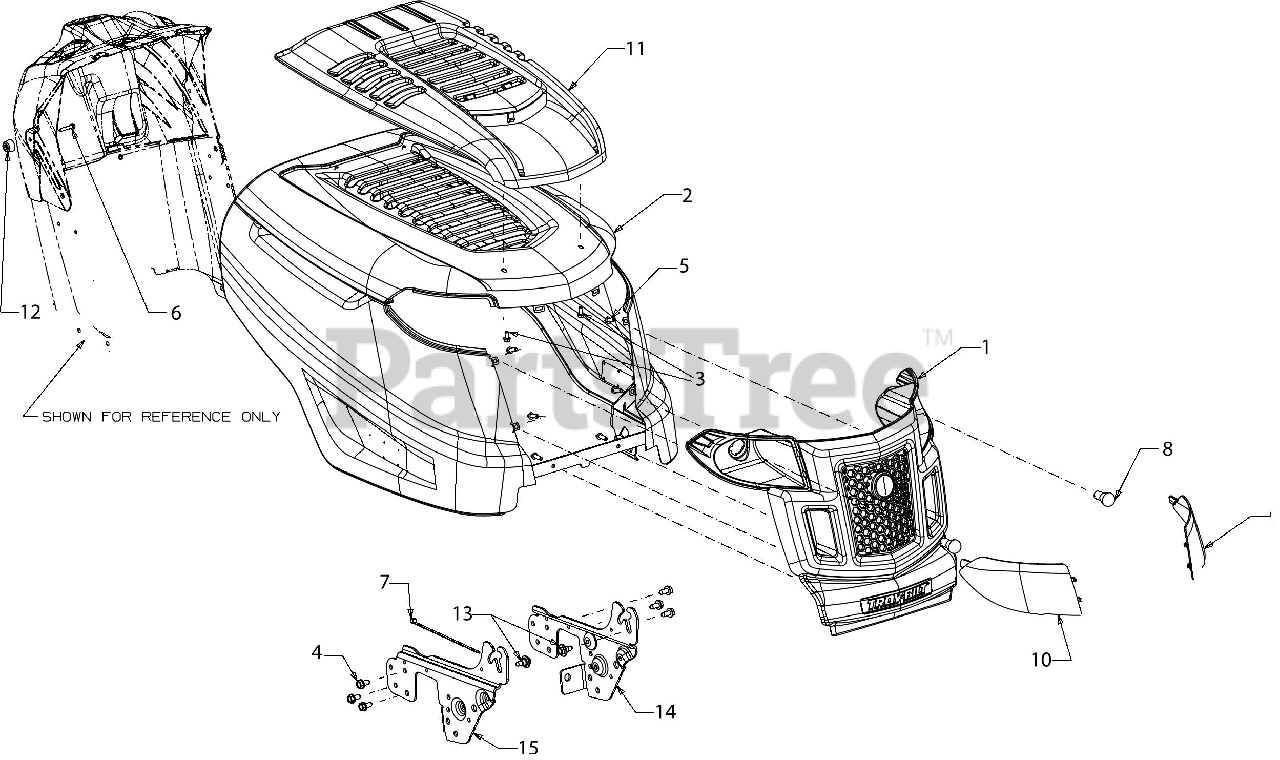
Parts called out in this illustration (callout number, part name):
1	GRILLE ASSEMBLY (TROY-BILT)
1	LABEL-TROYBILT/GEAR
3	HEX SCREW 1/4-15 x .50
4	SCREW 5/16-18 x .750
5	SCREW 1/4 x .750
6	SCREW #12 x 1.15
7	7" CABLE TIE
8	MINIATUURE BULB 12V
12	DASH BUMPER K STYLE
13	SHOULDER SCREW .43X.29X5/16-18 TT
